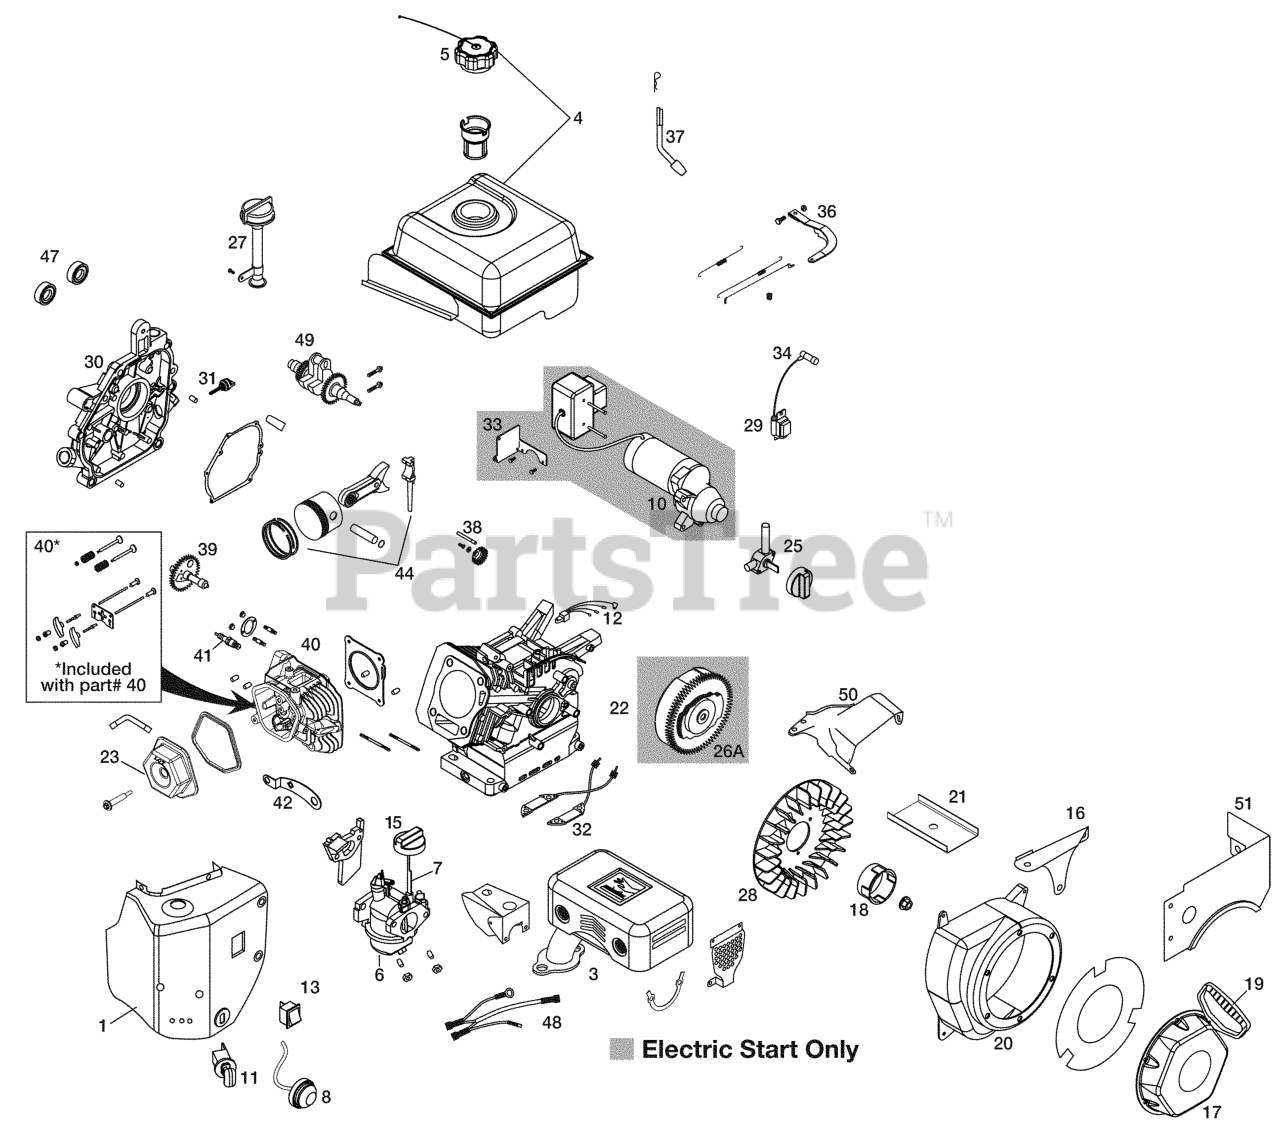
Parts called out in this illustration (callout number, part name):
1	HEATER.BOX.ASSY.SNOW(SKSN2100)
3	MUFFLER.ASSY.SNOW(SKSN4200)
4	FUEL.TANK.ASSY.SNOW(SKSN4300)
5	FUEL.TANK.CAP.SNOW(SKSN4301)
6	CARBURETOR.ASSY.SNOW(SKSN2302)
7	CHOKE.LVR.CARB-SNOW(SKSN2303)
8	PRIMER.BULB.ASSY(SKSN4304)
10	ELECTRIC.START.ASSY(SKSN2400.2
11	KEY.SWITCH.ASSY.SNOW(SKSN4401)
12	CDI.BOX.ASSY.SNOW(SKSN4404)
13	ON/OFF.SWITCH.SNOW(SKSN4403)
15	CHOKE.KNOW.SNOW(SKSN4500)
16	GOVERNOR.LINK.SHIELD(SKSN2501)
17	RECOIL.START.ASSY.(SKSN2600)
18	STARTER.CUP.SMALLSNOW(SKSN2601
19	STARTER.GRIP.SNOW(SKSN2603.1)
20	HOUSING.BLOWER.ASM
21	SHIELD.CYLINDER.SNOW(SK4141010
22	SHIELD.U/FYWHL.CHARG(SKSN4604)
23	VALVE.COVER.SNOW(SK25914500)
25	FUEL.PETCOCK.SNOW(SKSN4900)
26	FLYWHL.ASSY.ELECT.(SK2911701)
26A	FLYWHL.ASSY.MANUL.(SK2911700)
27	HIGHOIL.FILL.ASSY.KIT(SKSN4911
28	FLYWHEEL.FAN
29	IGNITION.COIL.ASSY
30	CRANKCASE.COVER.ASY(SK2913600)
31	NONREMVABLE.OIL.PLUG(SK4143715
32	CHARGING.COIL.AC/DC(SK4141710)
33	ELECTRIC.START.BRKT(SKSN4405)
34	SPARK.PLUG.BOOT(SK2913800.1)
36	GOVERNOR.ARM.ASSY.(SKSN2502)
37	GOVERNOR.SHAFT.(SK2913100)
38	GOVERNOR.GEAR.ASSY(SK2912900)
39	CAMSHAFT.LCT.291CC
40	CYLINDER.HEAD.ASSY(SK2911000)
41	SPARK.PLUG(SK2911550)
42	CDI.BOX.BRKT.SNOW(SKSN4402)
44	PISTON.AND.ROD.ASSY(SK2911400)
46	SHIELD.VAPOR(SKSN4606)
47	OIL.SEAL.KIT(SK2913900)
48	WIRE.HARNESS(SKSN4406)
49	CRANKSHAFT.LCT.291CC.SNOW
50	RP TOP SHIELD
51	FUEL.TANK.SKIRT(SKSN2101)
